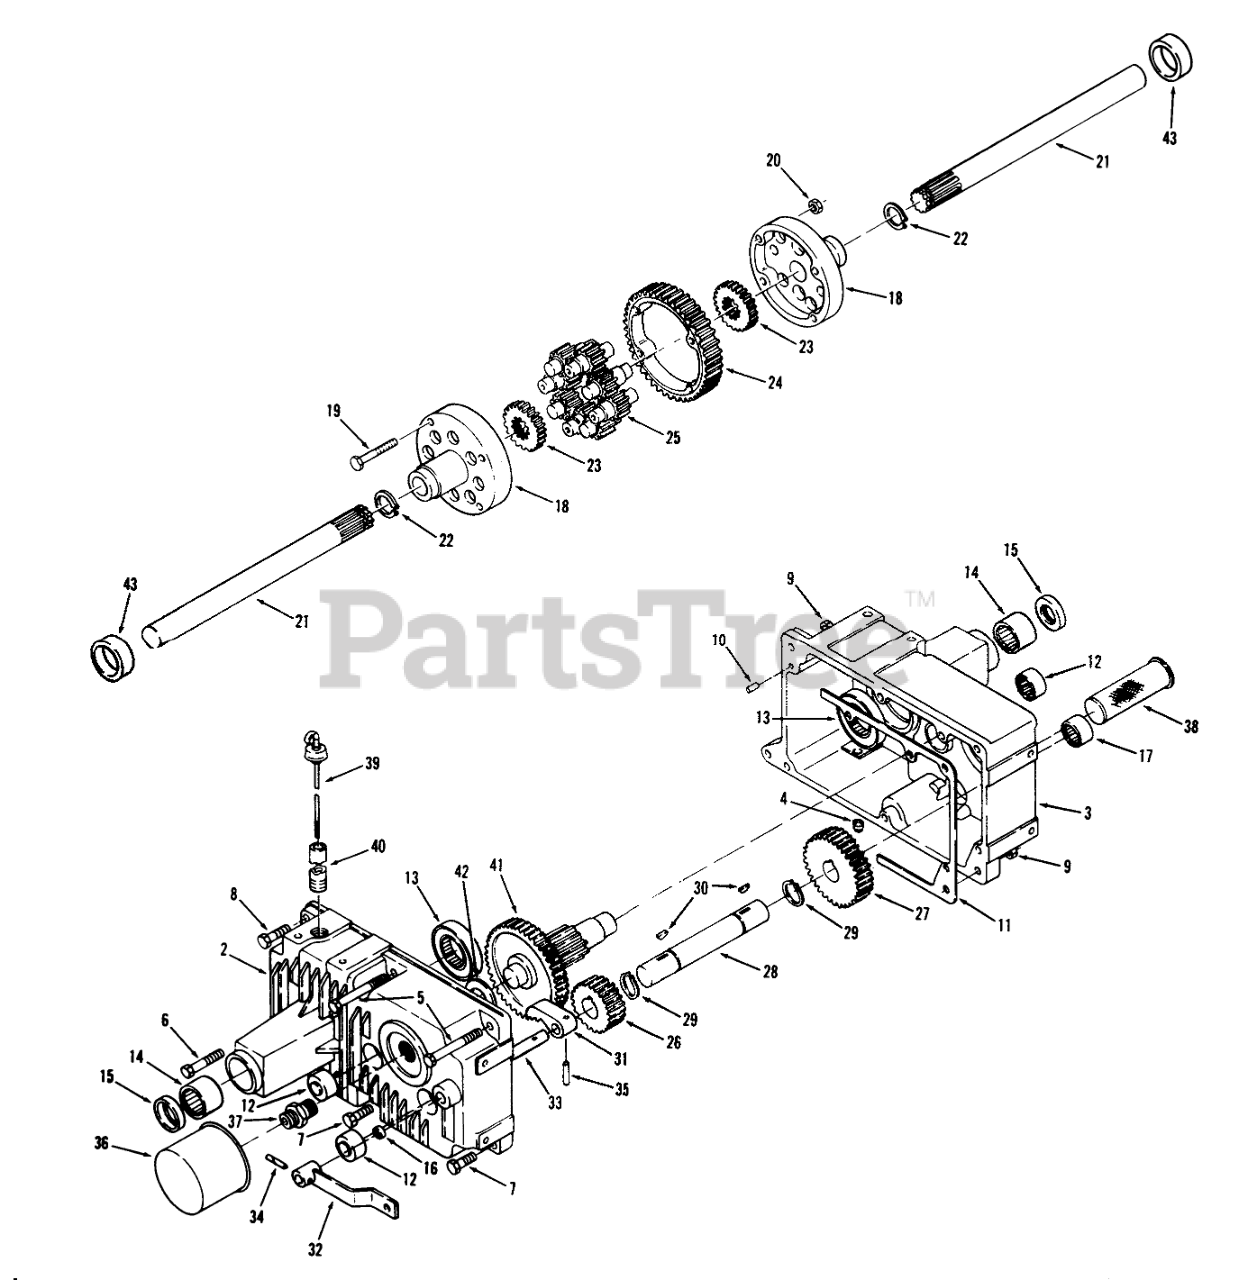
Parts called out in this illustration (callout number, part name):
1	Assy-Transaxle
2	RH TRANSMISSION CASE
3	Case LH
4	PLUG 1/4 PIPE ALLEN
5	H H C S
6	HHCS
7	Bolt
8	Bolt
9	Nut
10	PIN-DOWEL
11	GASKET
12	BEARING-NEEDLE
13	NEEDLE BEARING
14	Bearing-Axle
15	SEAL-OIL
16	SEAL BRAKE SHAFT
17	Needle Bearing
18	DIFFERENTIAL END CAP
19	BOLT-HEX
20	NUT
21	REAR AXLE
22	SNAP RING
23	GEAR-AXLE DIFFERENTIAL
24	GEAR-DIFFERENTIAL RING, 43T
25	GEAR-PINION, 11T
26	20T GEAR
27	Gear 44T
28	SHAFT GEAR
29	Snap Ring
30	Key
31	Parking Pawl
32	LEVER BRAKE ASSY
33	Parking Shaft
34	Pin-Roll
35	PIN-ROLL
36	Filter
37	FITTING
38	Strainer
39	Dipstick
40	Nipple
42	WASHER-THRUST
43	RACE BEARING
